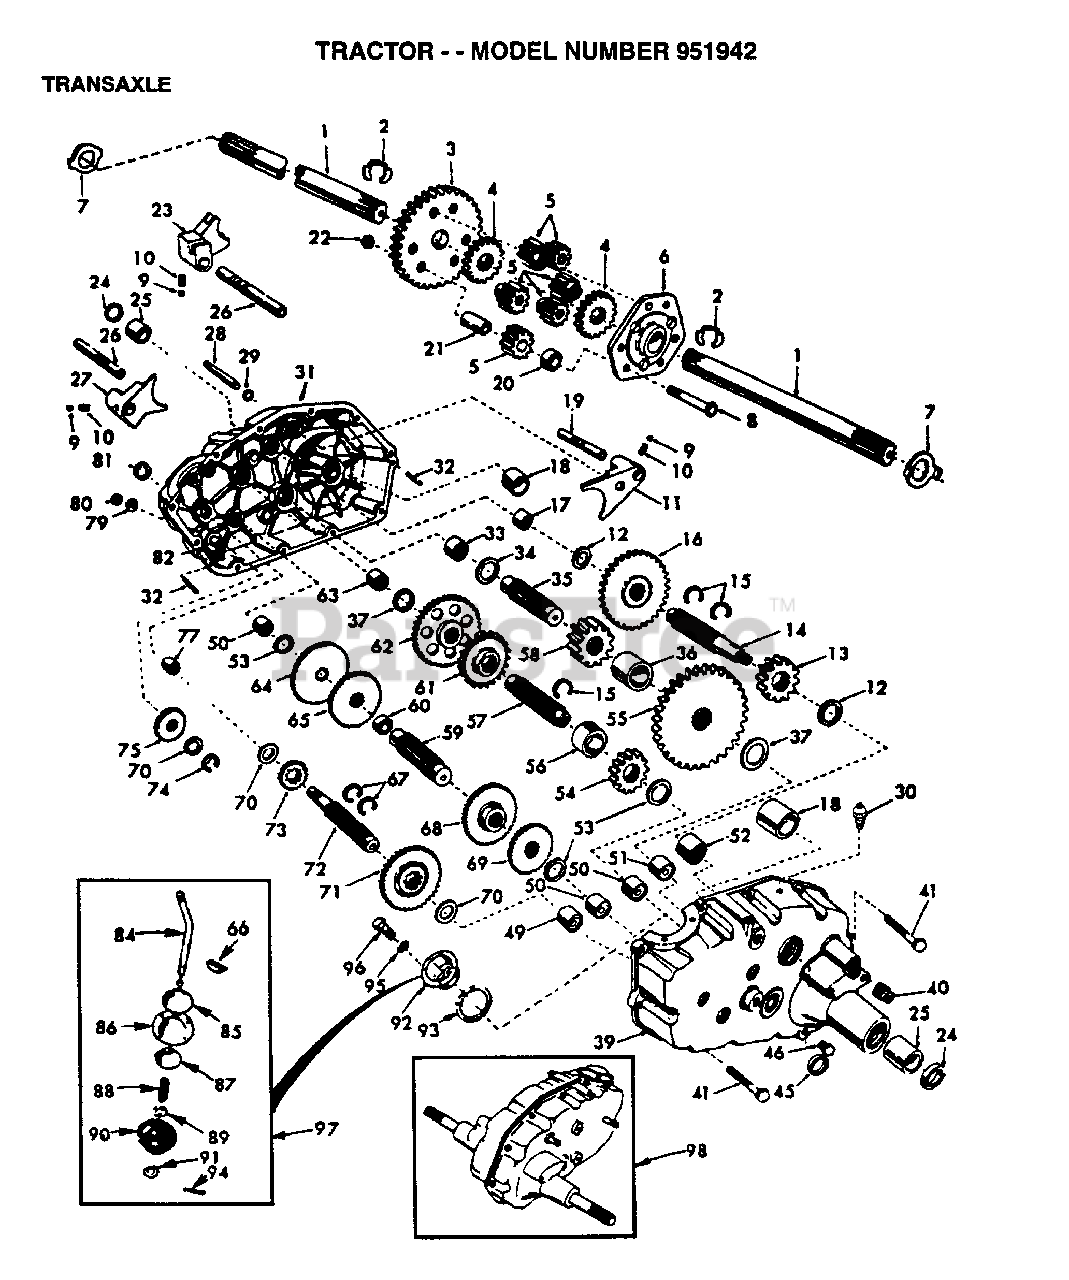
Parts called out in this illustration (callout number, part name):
1	SHAFT.AXLE.T
2	KLIP RING
3	FINAL GEAR T
4	DIFF GEAR T
5	DIFF PINION T
6	DIFF CARRIER T
8	BOLT
11	SHIFT FORK T
12	WASHER .T
13	RED PINION T
14	SHAFT BRAKE GT
15	SNAP RING T
16	GEAR T
17	"T, BEARING"
18	BEARING
19	SHAFT
20	SPACER T
21	PINION RS
22	GRIPCO NUT
23	FORK T
24	OIL SEAL STD
25	BRNG. T
26	SHIFT FORK SHAFT
27	SHIFT FORK T
28	SHIFT SHAFT
29	SEAL T
30	VALVE M
31	GEARCASE RH W/BER
32	PIN T
33	NEEDLE BRNG T
34	RACE T
35	GEAR SHAFT T
37	RACE T
39	GEARCASE LH W/BER
40	PLUG PIPE
41	BOLT.5/16-18X1.25
45	SEAL T
49	"TI, BEARING"
50	NEEDLE BRNG T
51	NEEDLE BRNG T
52	"STD, BEARING"
53	BRNG RACE
54	RED PINION T
55	RED GEAR T
56	PINION SPACER T
57	GEAR SHAFT T
58	FINAL PINION T
59	GEAR SHAFT T
60	SPACER T
61	RED PINION T
62	RED GEAR T
63	RACE T
64	LOW SPEED GEA T
65	REVERSE GEAR T
66	KEY T
67	KLIP RING
68	INTERMED GEAR T
70	"T, BEARING"
71	CLUSTER GEAR T
72	SHAFT INPUT
73	LO SPEED PINION T
74	KLIP RING
75	IDLER GEAR T
77	NEEDLE BEARING TI
79	WASHER T
80	NUT
81	SEAL STD
82	SHAFT REVERSE IDL
84	GEAR SHIFT LVR T
85	CAP T
86	COVER AND PIN T
87	GUIDE BALL T
88	SPRING TI
89	WASHER
90	SEAL T
91	WASHER
92	GEAR SHIFT GA T
93	GASKET T
94	COTTER PIN
95	LOCKWASHER
96	BOLT
97	GEAR SHFT LVR T
